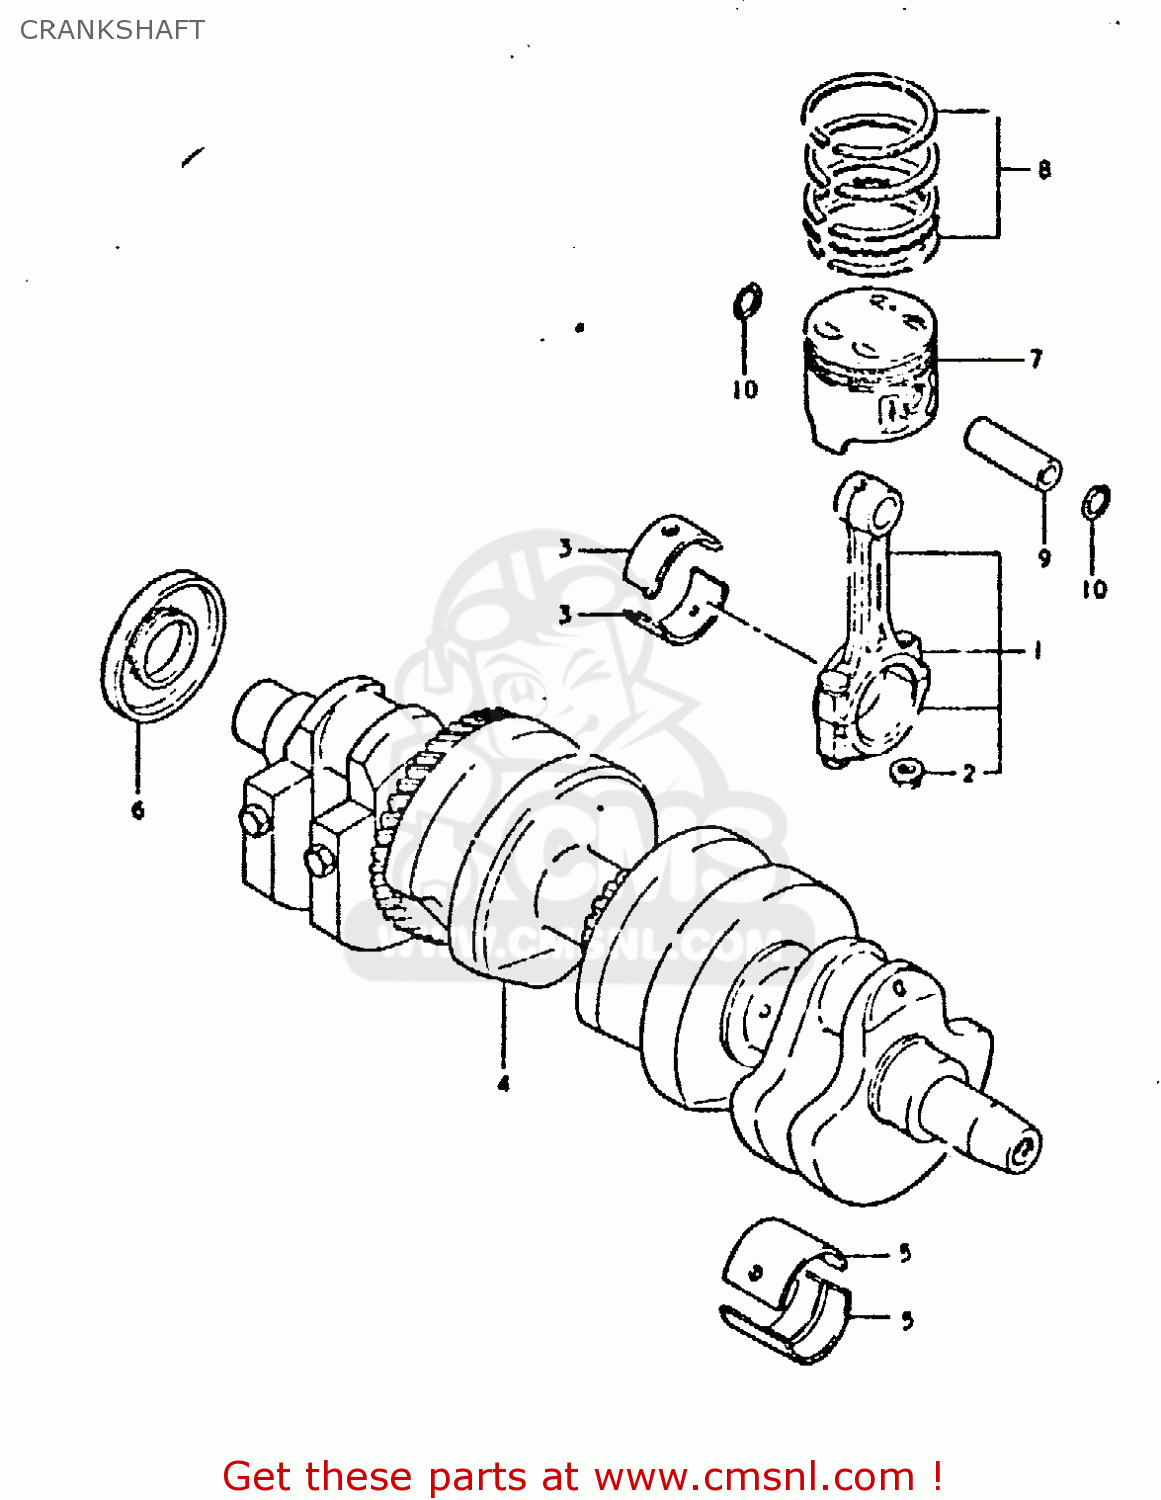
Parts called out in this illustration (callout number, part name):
1	CONNECTING ROD ASSEMBLY
2	NUT
3	BEARING,CRANK PIN
4	CRANKSHAFT
5	METAL CRANKSHAFT
6	OIL SEAL
7	PISTON
8	RING SET,PISTON
9	PIN,PISTON (18MM)
10	CIRCLIP,PISTON PIN
